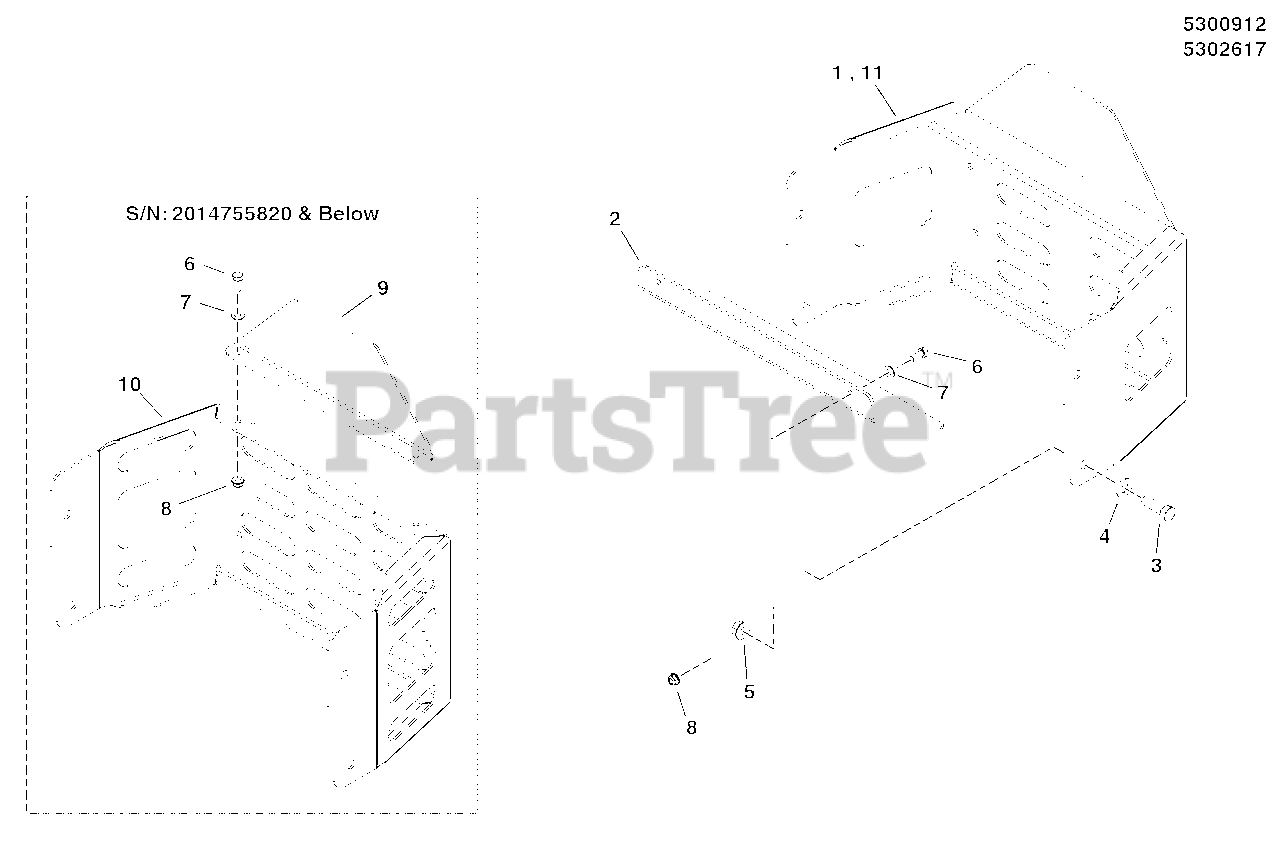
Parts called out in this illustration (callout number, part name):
1	WELD, PLATE, BUMPER - RED
2	SHIELD, MUFFLER - BLK
3	BOLT, 1/2-13 X 1-1/2 GD5 CZ
4	WASHER, 1/2 SAE
5	NUT, 1/2-13 HEX NYLOCK FLANGE
6	BOLT, 5/16-18 X 3/4 GD5
7	WASHER, 5/16" SAE
8	NUT, 5/16-18 HEX NYLOCK FLANGE
9	PLATE, CARB GUARD - RED
10	WELD, PLATE, BUMPER - RED
11	WELD, PLATE, BUMPER - RED
